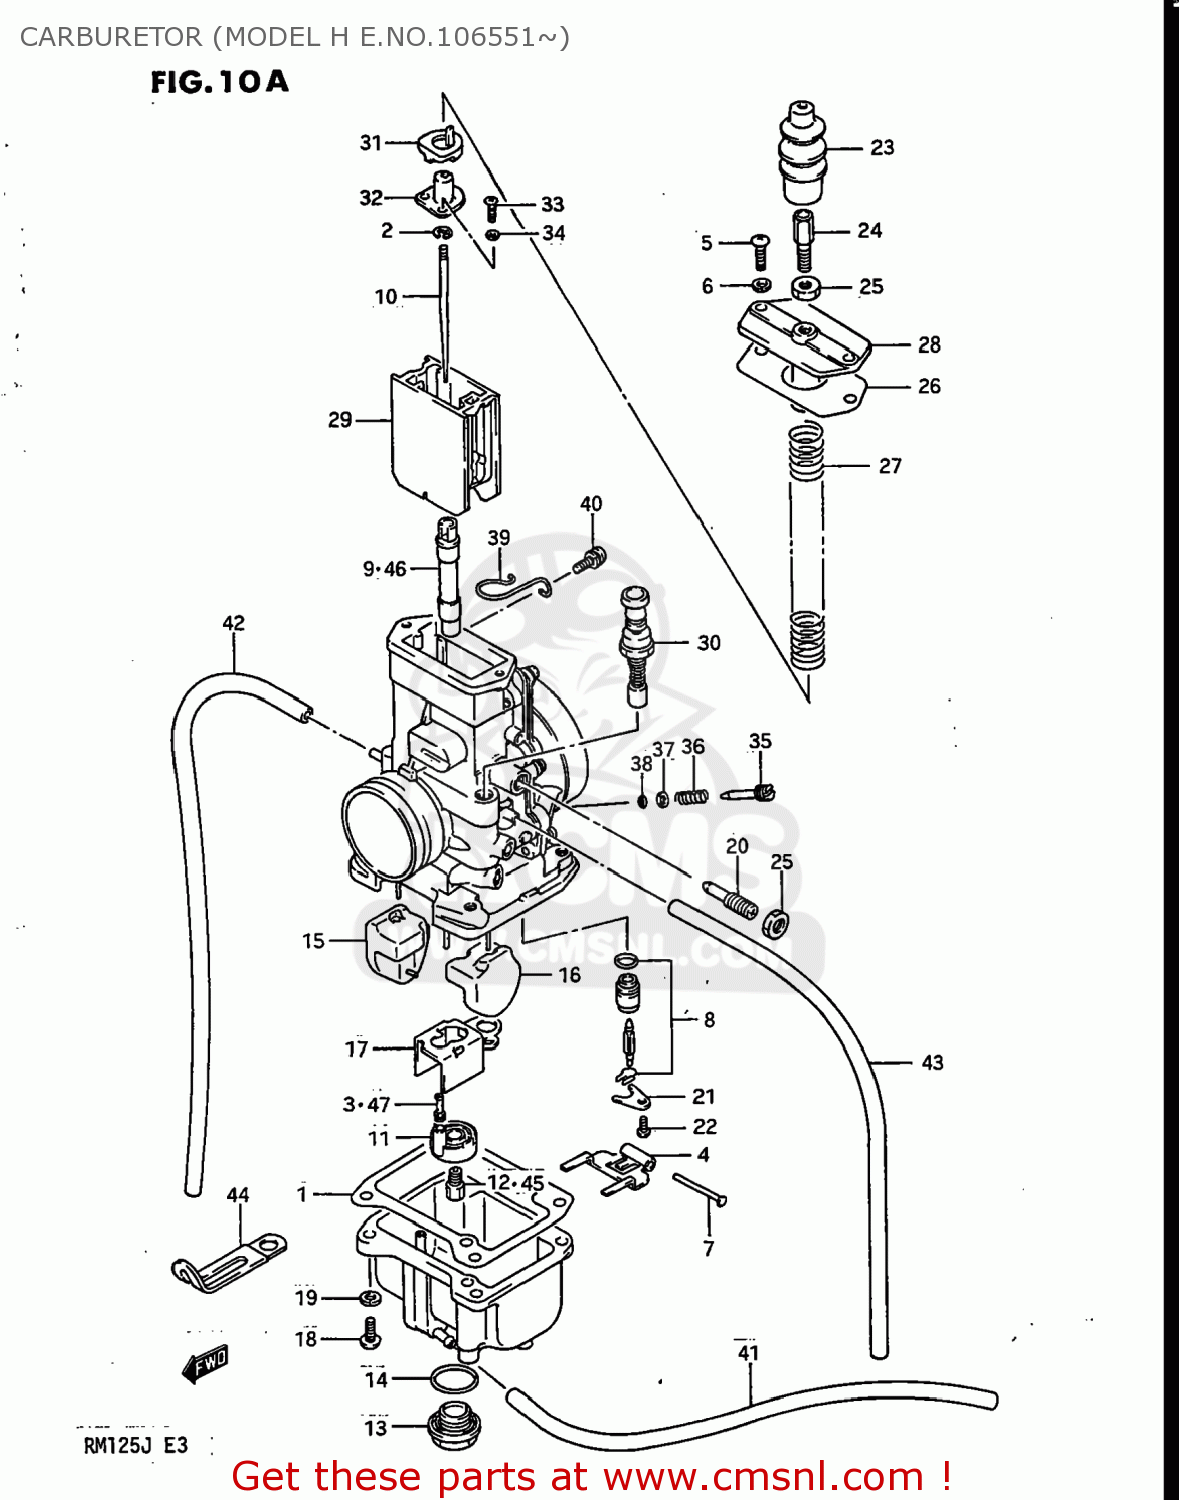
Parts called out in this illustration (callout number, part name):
1	GASKET,FLOAT CAHMBER (NAS)
2	CLIP,NEEDLE
3	JET
4	ARM,FLOAT
5	SCREW
6	LOCK WASHER
7	PIN,FLOAT
8	VALVE ASSEMBLY,NEEDLE
9	JET,NEEDLE
10	NEEDLE JET
11	RING
12	JET,MAIN(330)
13	SCREW,GUIDE
14	O RING,DRAIN PLUG
15	FLOAT,R
16	FLOAT,L
17	PLATE
18	SCREW
19	LOCK WASHER
20	SCREW,THROTTLE SCREW
21	PLATE
22	SCREW
23	CAP,CABLE ADJUSTER
24	ADJUSTER,CABLE
25	NUT
26	GASKET,TOP (NAS)
27	SPRING,THROTTLE VALVE
28	CAP,CARBURETOR,TOP
29	VALVE,PISTON (CA:6.0)
30	PLUNGER ASSEMBLY
31	RING
32	JOINT
33	SCREW
34	LOCK WASHER
35	SCREW,PILOT AIR
36	SPRING,THROTTLE SCREW
37	GASKET
38	O RING,PILOT AIR SCREW
39	CLIP
40	SCREW
41	HOSE
42	HOSE
43	HOSE
44	CLAMP L:35
45	JET,MAIN(290)
46	JET,NEEDLE
47	JET,PILOT 20
